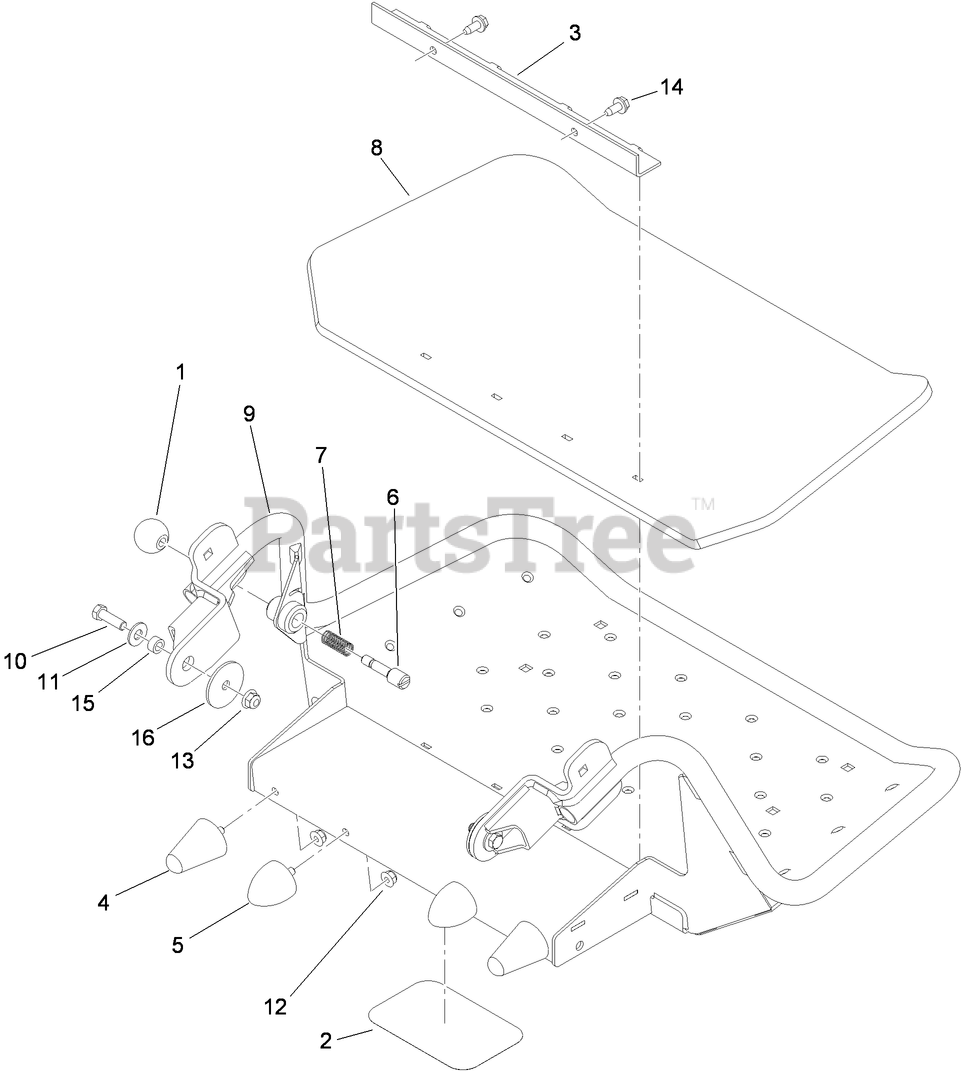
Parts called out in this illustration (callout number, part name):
1	KNOB-BALL
2	DECAL
3	CLAMP-SHIELD
4	BUMPER-RUBBER
5	BUMPER-RUBBER
6	PIN-LATCH
7	SPRING
8	MAT-FOOT
9	PLATFORM
10	SCREW-HH
11	WASHER-FLAT
12	NUT-HF, NI
13	NUT-HF, NI
14	SCREW-HWHTF
15	SPACER
16	WASHER-FLAT
